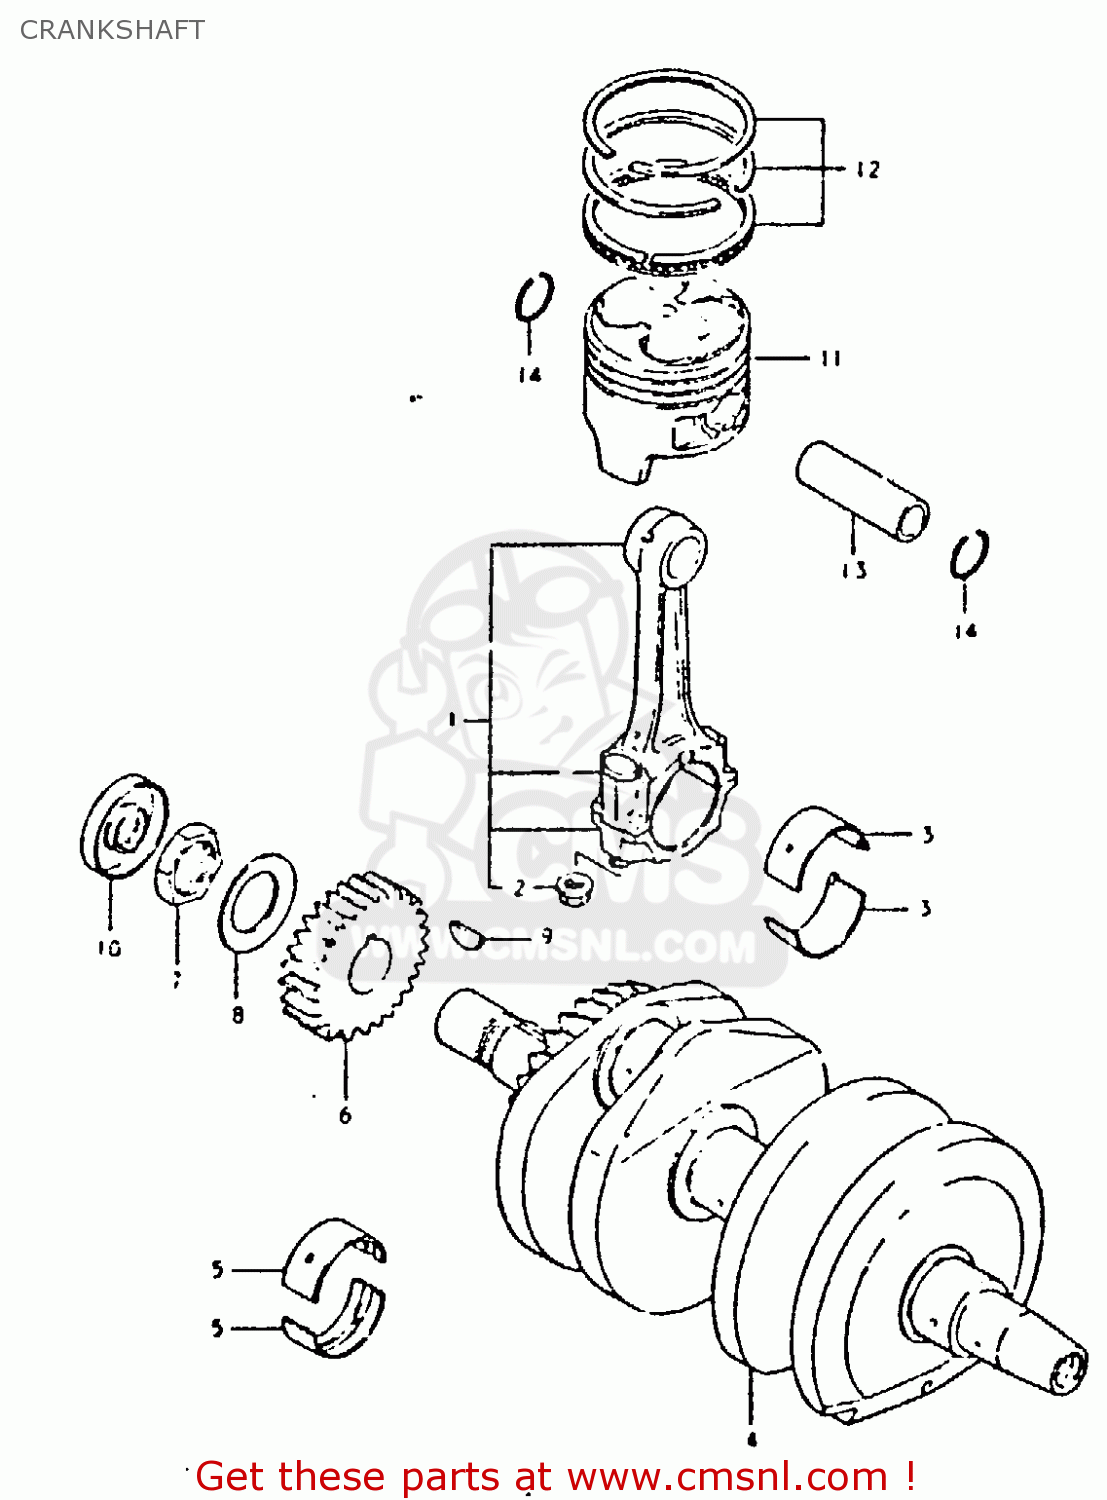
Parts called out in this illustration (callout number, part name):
1	ROD ASSY, CONNECTING
2	NUT
3	BEARING,CRANK PIN GREEN
4	CRANKSHAFT ASSEMBLY
5	METAL CRANKSHAFT
6	GEAR,PRIMARY DRIVE
7	NUT
8	WASHER
9	KEY
10	OIL SEAL
11	PISTON
12	RING SET,PISTON
13	PIN,PISTON
14	CIRCLIP
